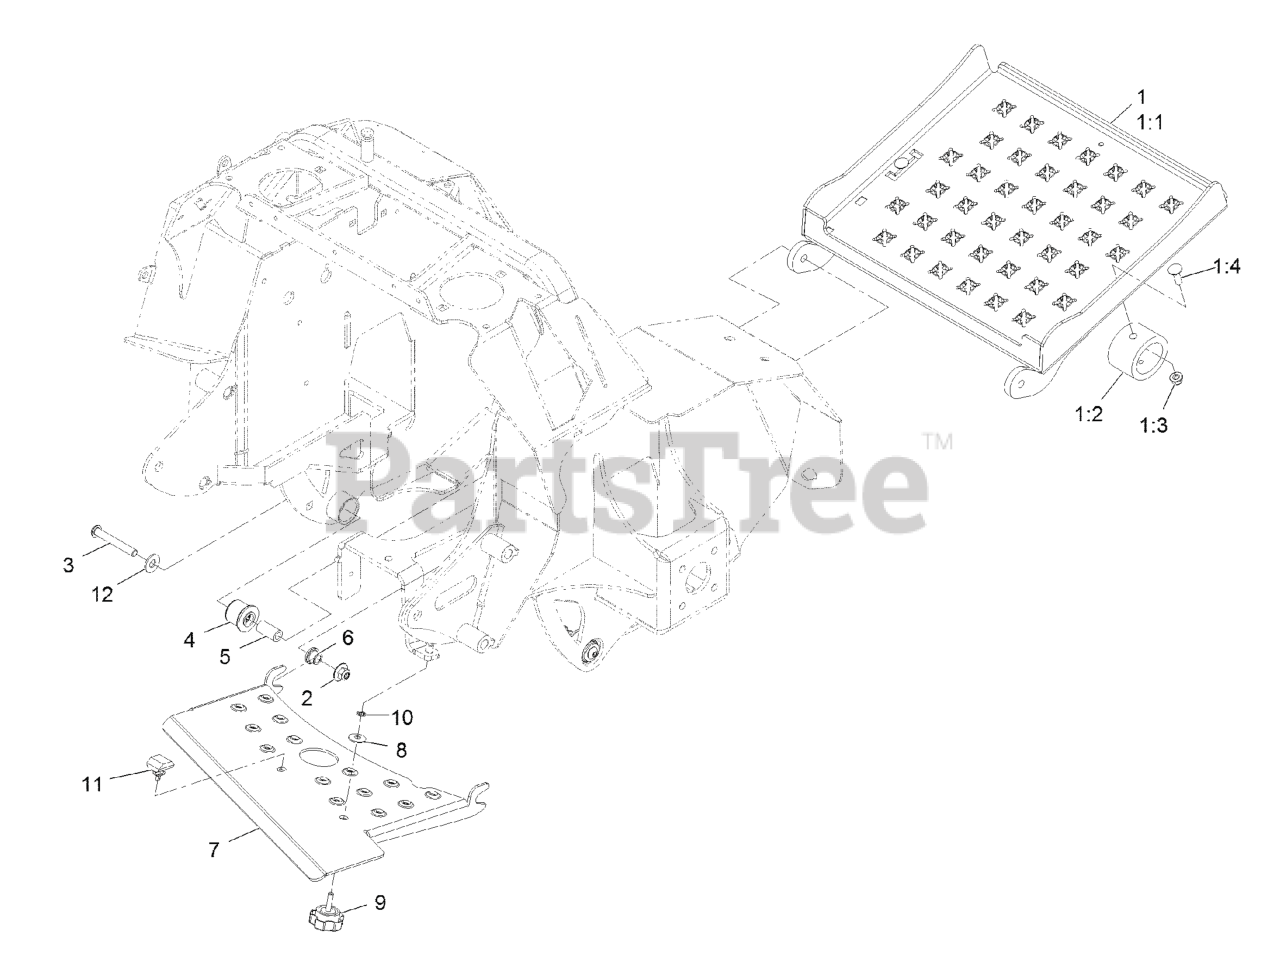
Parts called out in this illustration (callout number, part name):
1:2	BUMPER-ISOLATOR
1:3	NUT-HF, NI
1:4	BOLT-CARR
2	Nut-Nyloc 3/8-16 Flg
3	SCREW-HSBH
4	BUSHING-RUBBER, SUSPENSION
6	BUSHING-FLANGED
7	DEFLECTOR-AIR, 32
8	WASHER-BELLEVILLE
10	NUT-RETAINING
11	BUMPER-ROPS
12	WASHER-FLAT
